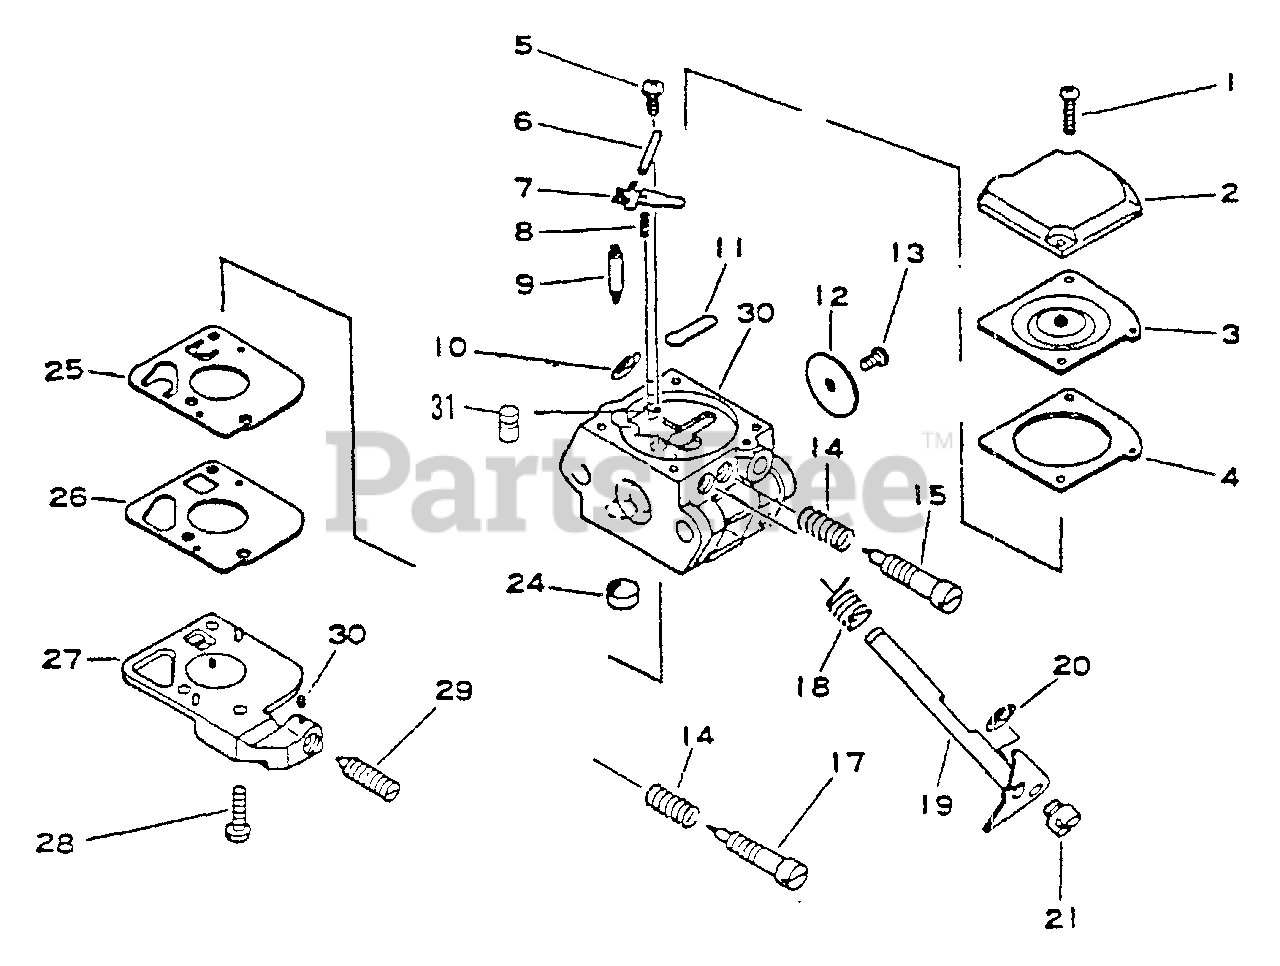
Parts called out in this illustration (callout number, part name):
2	COVER, DIAPHRAGM
3	DIAPHRAGM
4	GASKET, METERING
6	PIN, METERING LEVER
7	LEVER, METERING
8	SPRING
11	PLUG, WELCH
12	VALVE, THROTTLE
14	SPRING, NEEDLE
15	NEEDLE, HIGH SPEED
17	NEEDLE, IDLE
18	SPRING, THROTTLE RETURN
19	SHAFT, THROTTLE
24	STRAINER
27	COVER, PUMP
29	SCREW, IDLE ADJUST
30	PIECE, FRICTION
31	NOZZLE, CHECK VALVE
